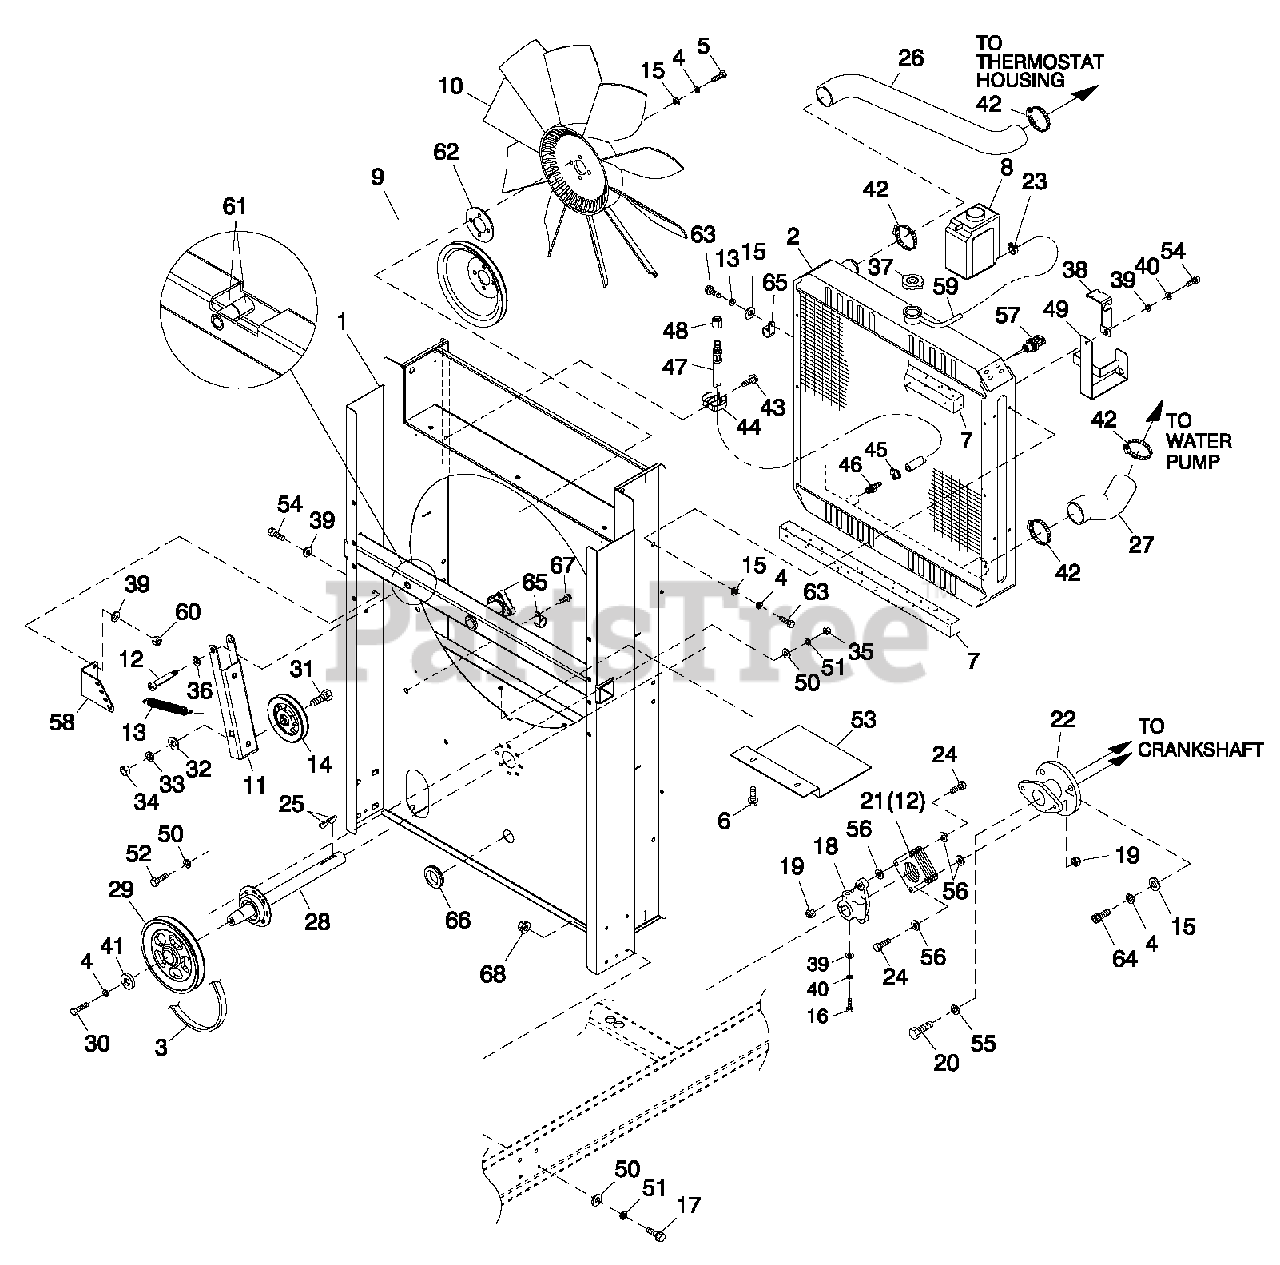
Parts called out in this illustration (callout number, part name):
1	WELDMENT RADIATOR SUPPORT C5
2	RADIATOR 680 X 680 X 70 CPL
3	V-BELT 31/64" X 62-3/8"
4	WASHER LOCK M10
5	SCREW HHC M10-1.5X30C10.9
6	SCREW THF M6-1 X 16 N WA Z/JS
7	TAPE FOAM 1 X 1 (26.75" LG)
8	TANK COOLANT RECOVERY
9	PULLEY FAN V-GROOVE 9"
10	FAN 26" LH ROTATION
11	ARM BELTTENSIONER
12	SHOULDER BOLT 1/2 X 2-1/4"
13	SPRING TENSION CPL
14	PULLEY V-BELT 4" FLANGED
15	WASHER FLAT 3/8-M10 ZINC
16	SCREW HHC M8-1.25X45C8.8
17	SCREW HHFC M6-1.0X20 G8.8
18	HUB FLEX PLATE
19	NUT HEX LOCK 5/16-24 NY INS
20	SCREW HHC M12-1.5X60G8.8
21	DISK FLEX
22	COUPLING HUB FLEX (MACH)
23	CLAMP HOSE BAND 1/4
24	SCREW HHC 5/16-24X1.124
25	KEY WOODRUFF 4X 1 9D
26	HOSE RADIATOR UPPER CPL
27	HOSE LOWER RAD CPL C5 6.8L
28	ASSY BRG/SHAFT CPL FANDRIVE
29	PULLEY 6.5" DIA MACHINED (6.8L 100KW)
30	SCREW HHC M10-1.5X30G8.8
31	SCREW HHC 1/2-13X 2" G8
32	WASHER FLAT 1/2 ZINC
33	WASHER LOCK 1/2
34	NUT HEX 1/2-13 STEEL
35	NUT HEX M 6X 1.0 G8YEL CHR
36	WASHER NYLON .50 X .87 X .06
37	CAP RADIATOR 13 PSI
38	BRACKET, SIGNAL CONDITIONER
39	WASHER FLAT 5/16-M8 ZINC
40	WASHER LOCK M8-5/16
41	SPACER .5 X 1.5 X .25 STL/ZINC
42	CLAMP HOSE #28 1.32-2.25
43	SCREW HHTT M 4 -0 .7X 8B P
44	SPRING CLIP HOLDER .37-.62
45	CLAMP HOSE .38-.87
46	BARBED STR 3/8 N PTX3/8
47	HOSE DRAIN ASSY 28"
48	CAP HEX 1/4 NPT BRASS
49	BRACKET COOLANT TANK
50	WASHER FLAT 1/4-M6 ZINC
51	WASHER LOCK M6-1/4
52	SCREW HHC M 6-1.0X 20G 8.8
53	SHIELD RADIATOR
54	SCREW HHC M8-1.25X20G8.8
55	WASHER LOCK M12
56	WASHER FLEX (THIN)
57	PROBE COOLANT LEVEL 3/8-18NPTF
58	BRACKET TENSIONER SPRING
59	HOSE 9/32 ID (43"LG)
60	NUT HEX LOCK M8-1.25 NY INS
61	BEARING SLEEVE 1/2/ X 3/4 X 1
62	SPACER CPL COOLING FAN 1/8"
63	SCREW HHC M10-1.5X20C8.8
64	SCREW SHC M10-1.5X 35 G12.9
65	CLAMP STL/VNL.62 X .406 Z
66	GROMMET 1.37 X .06 X 1.00
67	SCREW HHTT M6-1.0X16ZYC
68	NUT FLANGE M6-1.0 NYLOK
